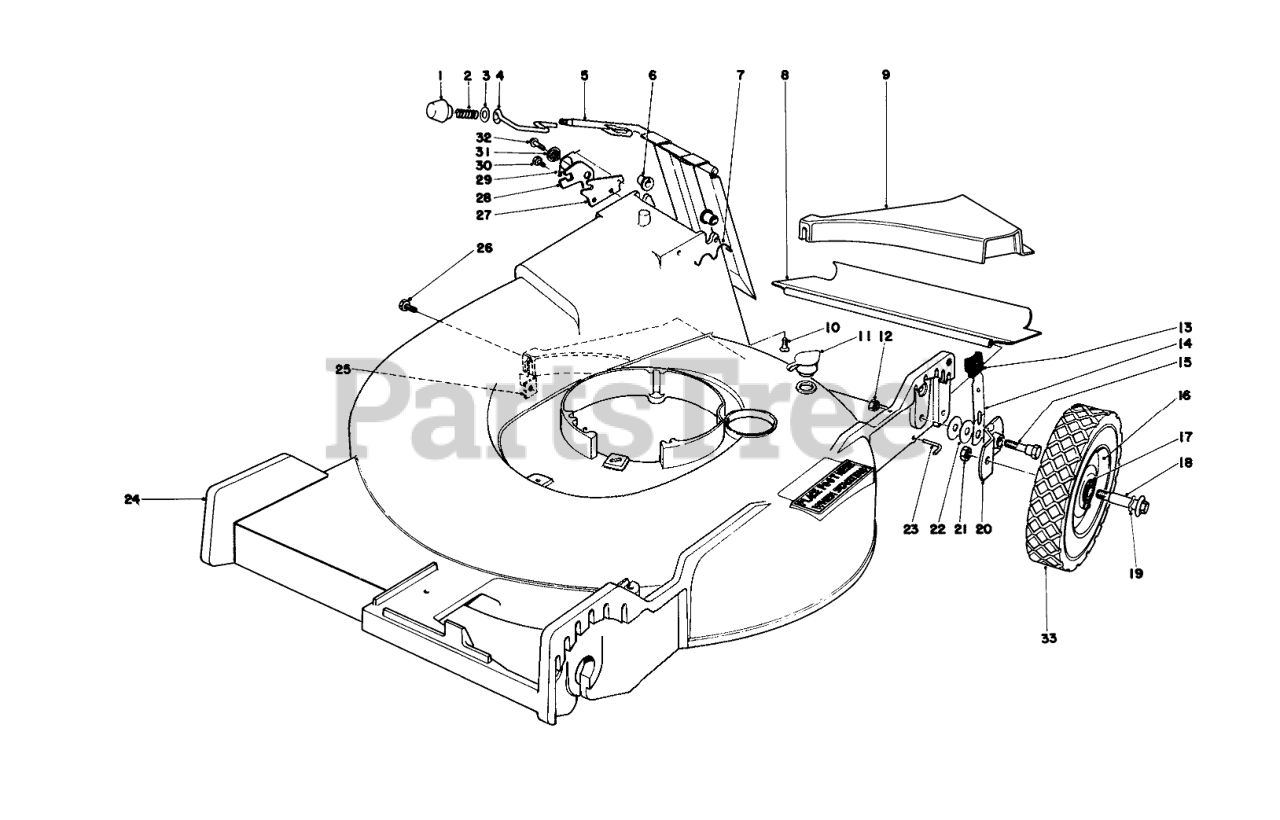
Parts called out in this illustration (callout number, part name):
2	COMPRESSION SPRING
3	WASHER
4	DOOR LATCH
5	Door Handle
6	BUSHING-NYLON
7	Door Retainer
8	REAR SAFETY SHIELD
9	REAR INSERT
10	SCREW-HH
11	WASHOUT PLUG
12	Nut
13	KNOB-ARM
14	SPRING ARM ASM
15	PIVOT SCREW
16	Wheel & Tire Assembly (Incl. Ref. #17 & 33)
17	BEARING-BALL
19	SPRING WASHER
20	PIVOT ARM ASM A
21	Nut
22	WASHER-PIVOT
23	ROD-SHIELD
24	Housing
25	SPECIAL NUT
26	SCREW THD 1/4 20 5/8
27	DOOR LATCH PLATE
28	Latch Safety
29	TORSION SPRING
30	SCREW-HWH
31	Latch Spacer
32	Screw
